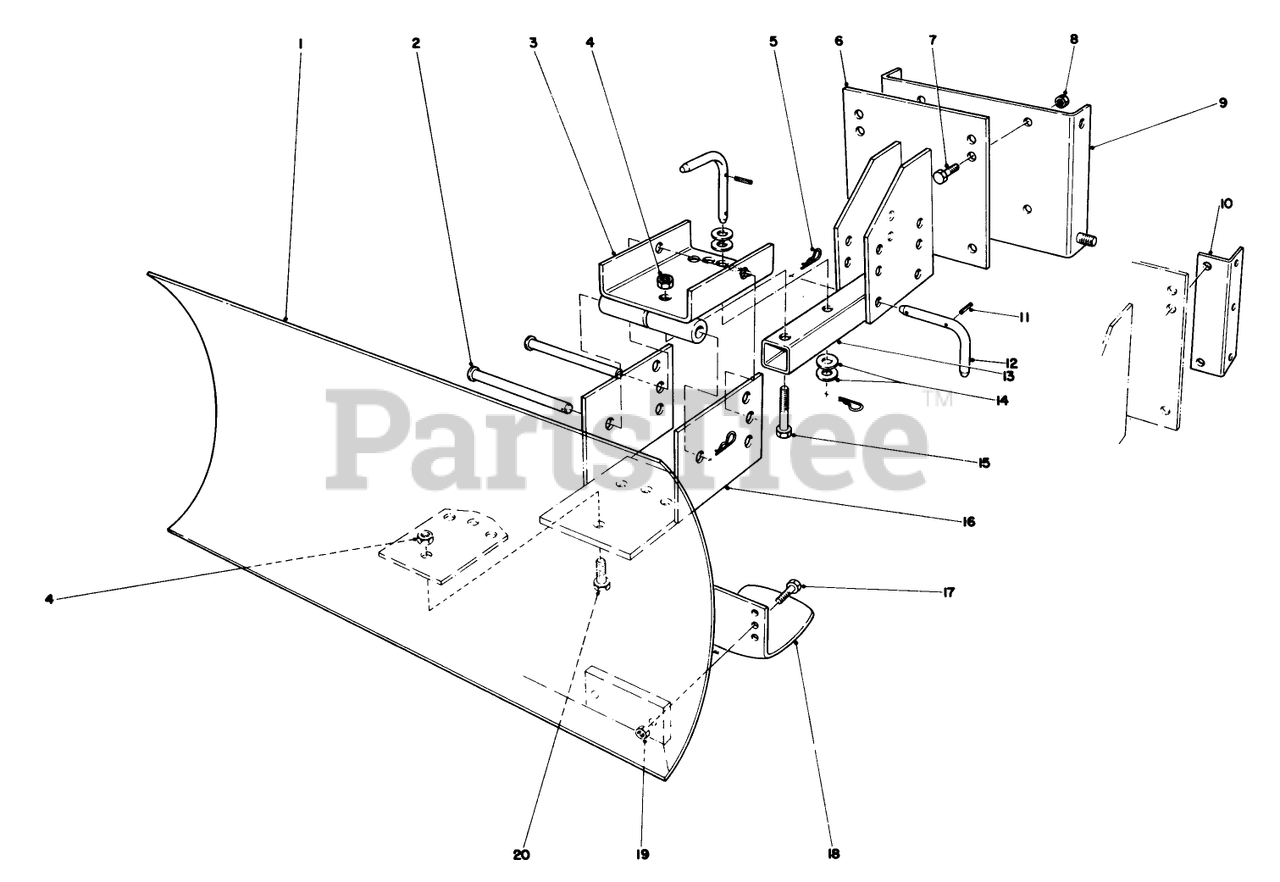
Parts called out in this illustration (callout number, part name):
1	Blade
2	PIN-CLEVIS
5	PIN-HAIR
7	SCREW-HH
8	NUT-LOCK, CONE
9	Mounting Plate (Used with 826 1132 Units only)
11	Pin-Roll
14	WASHER-FLAT
15	SCREW-HH
17	SCREW-HH
19	NUT-LOCK, CONE
20	SCREW-HH
